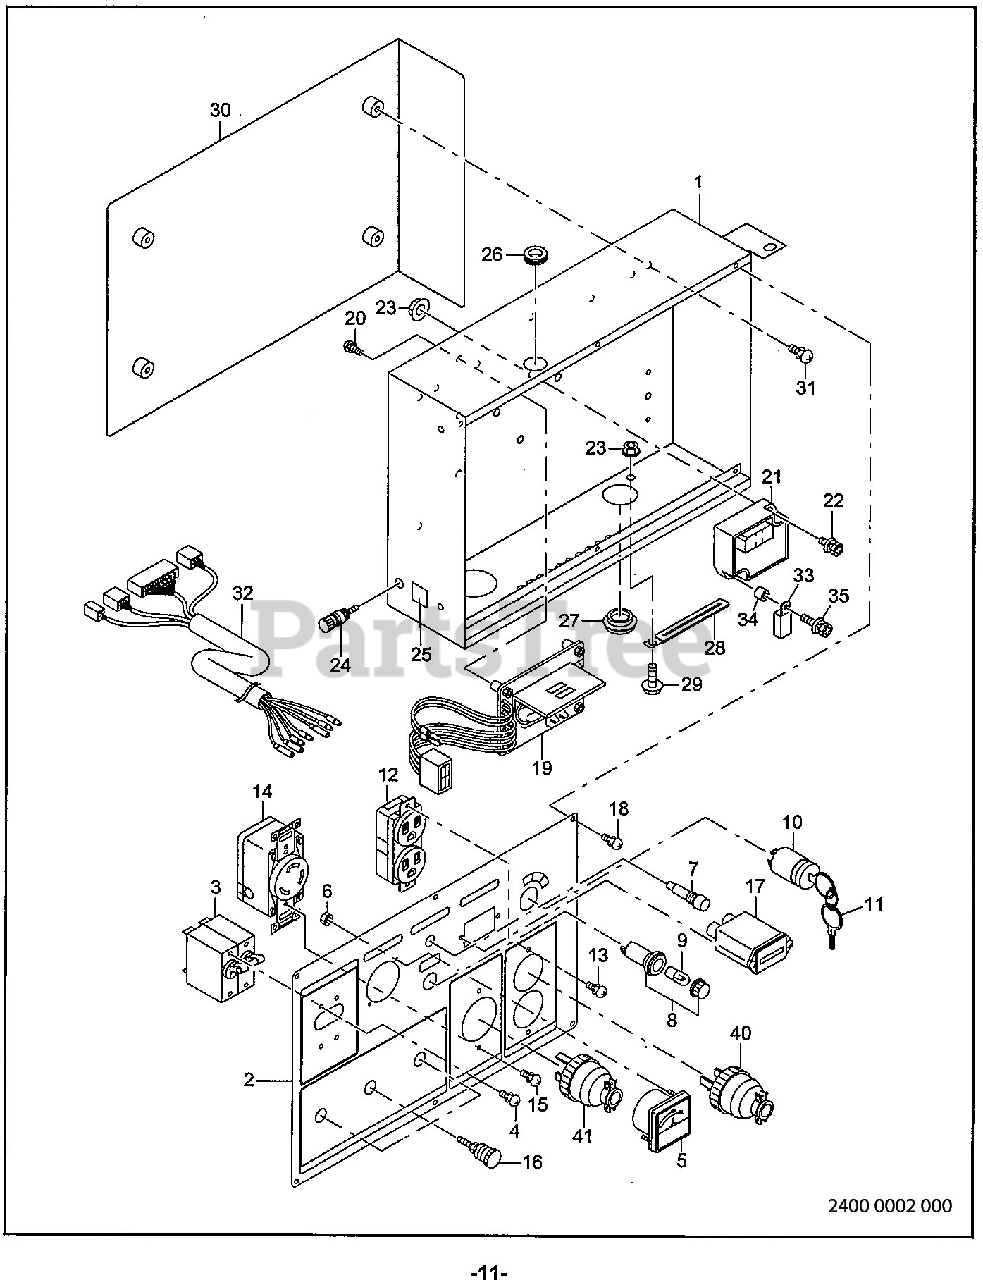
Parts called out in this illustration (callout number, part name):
1	CONTROL BOX ASSY
1	CONTROL BOX UNIT
2	CONTROL PANEL ASSY
2	CONTROL PANEL
3	BREAKER C2P-39A)
4	SCREW and WASHER ASSY
8	LAMP (OIL)
9	LAMP (18V-0.11A)
10	KEY SWITCH
12	AC RECEPTACLE (125V-15A)
13	SCREW and WASHER ASSY
14	AC RECEPTACLE (250V-30A, TWIST LOCK)
15	SCREW and WASHER ASSY
16	TERMINAL
18	SCREW and WASHER ASSY
20	SCREW and WASHER ASSY
21	ECU(O/S & R/C) ASSY
22	SCREW and WASHER ASSY
23	FLANGE NUT
29	FLANGE BOLT
31	SCREW and WASHER ASSY
32	WIRE ASSY
35	SCREW
40	AC PLUG (250V-15A)
41	AC PLUG (250V-30A)
